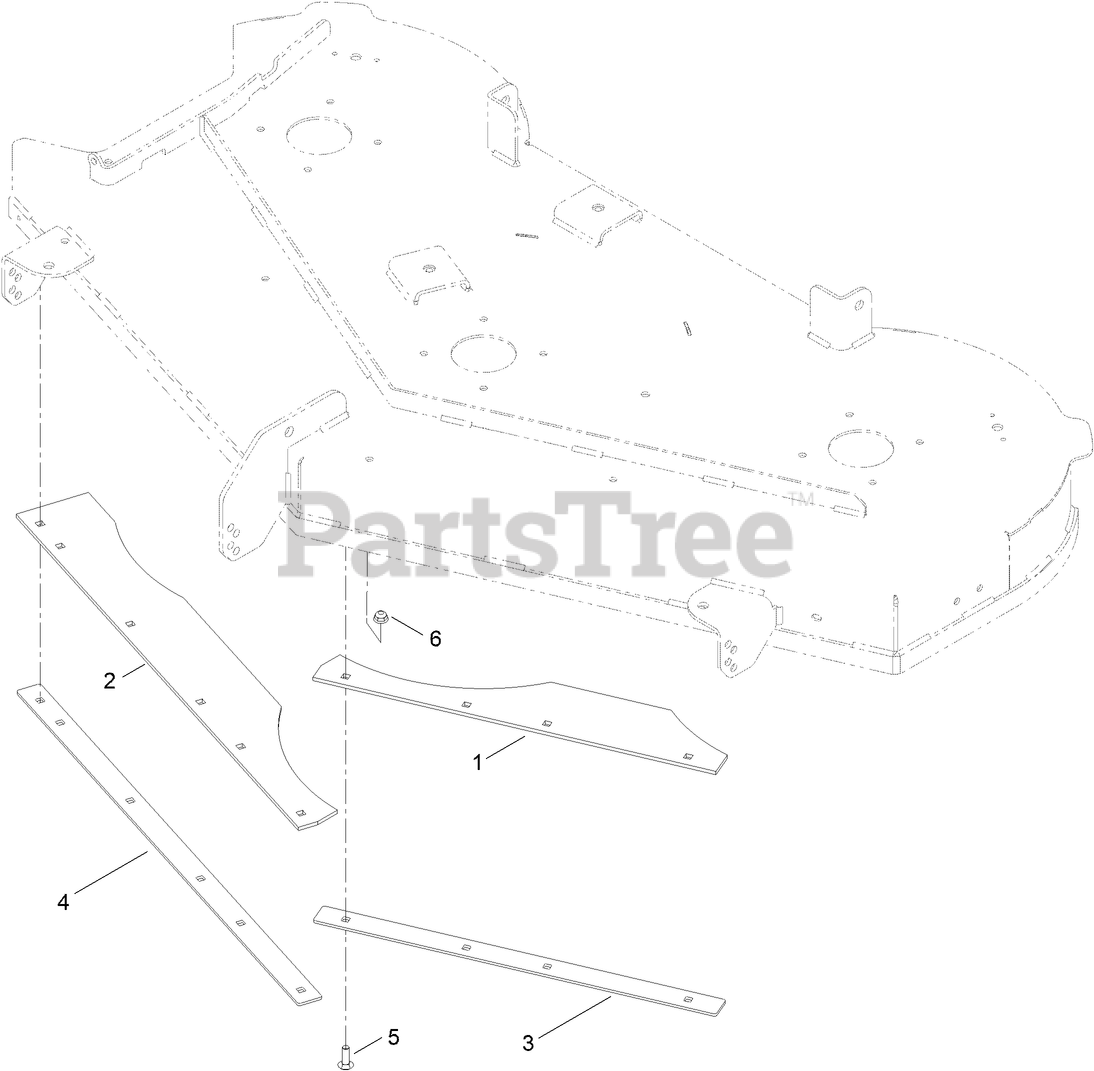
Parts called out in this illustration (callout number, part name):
1	SKIRT-RUBBER, FRONT
2	SKIRT-RUBBER, FRONT
3	PLATE-SKIRT
4	PLATE-SKIRT
5	SCREW-CARR
6	NUT-HF
